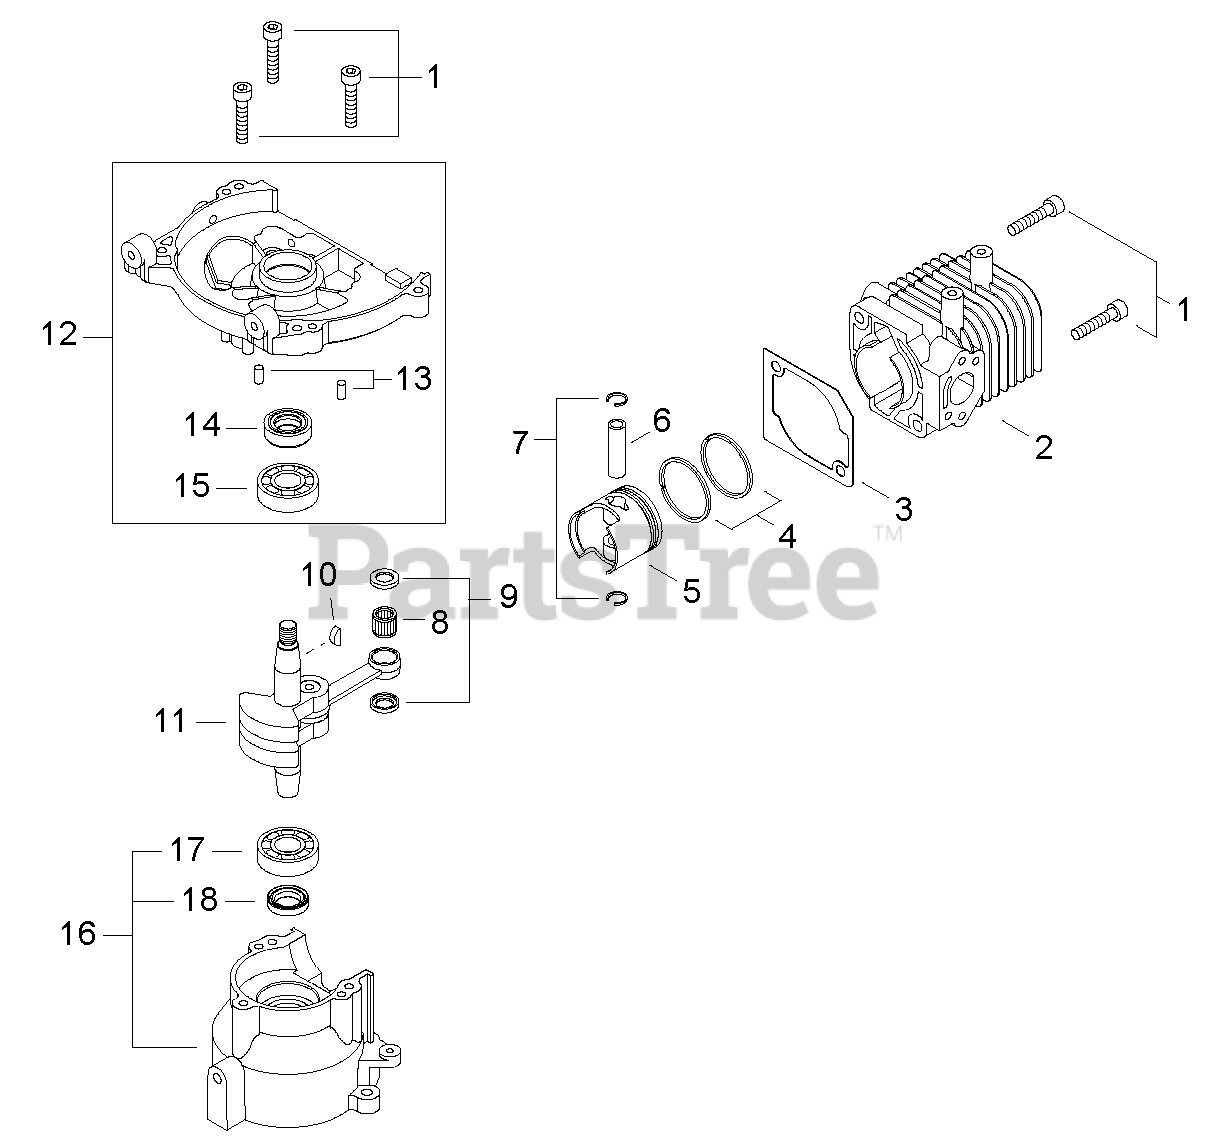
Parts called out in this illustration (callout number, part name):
1	SCREW - 5X25
2	CYLINDER
3	GASKET, CYLINDER
4	RING, PISTON
6	PIN, PISTON
7	RING, RETAINING
8	BEARING, NEEDLE - 8
9	SPACER, PISTON
10	KEY - 3X10
11	CRANKSHAFT ASSY
12	CRANKCASE ASSY - FRONT
13	PIN - LOCATING
14	SEAL, OIL - 12
15	BEARING, BALL - 6001C3
16	CRANKCASE ASSY
17	BEARING, BALL - 6001C3
18	SEAL, OIL - 12
